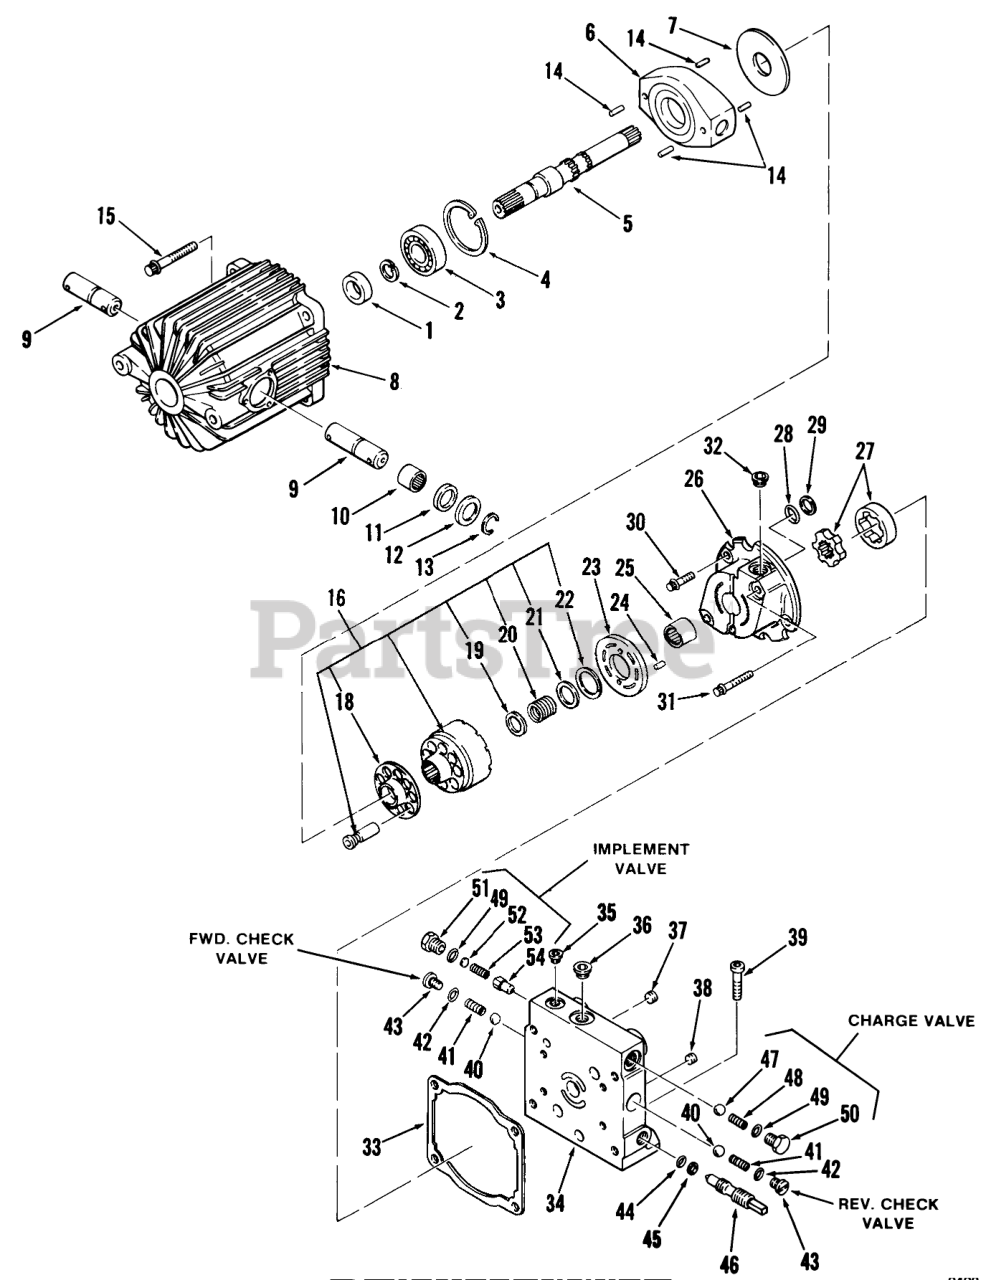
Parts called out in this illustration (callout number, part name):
22	RING-SUN9006250-0112
23	PLATE-VALVE
28	O RING
29	RING BACKUP
42	O RING
44	O-RING
46	VALVE
49	O RING
